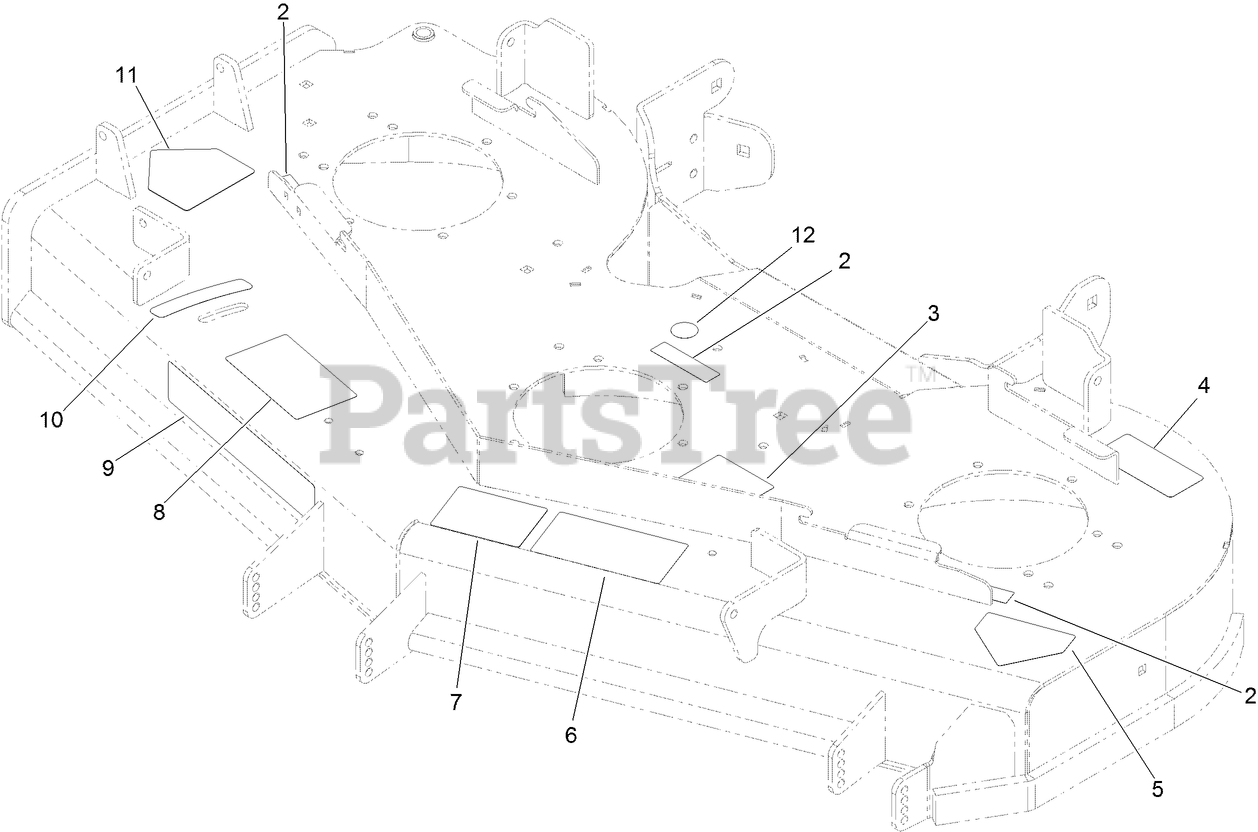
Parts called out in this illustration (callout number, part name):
2	DECAL-COVER, MISSING
3	DECAL-ROUTING, DECK BELT
4	DECAL-TORQUE
5	DECAL-DANGER
6	DECAL-DANGER, THROWN OBJECT
7	DECAL-SCALP, ANTI
8	DECAL-ADJUSTMENT, BAFFLE
10	DECAL-SETTING, BAFFLE
11	DECAL-DANGER
12	DECAL-GREASE
